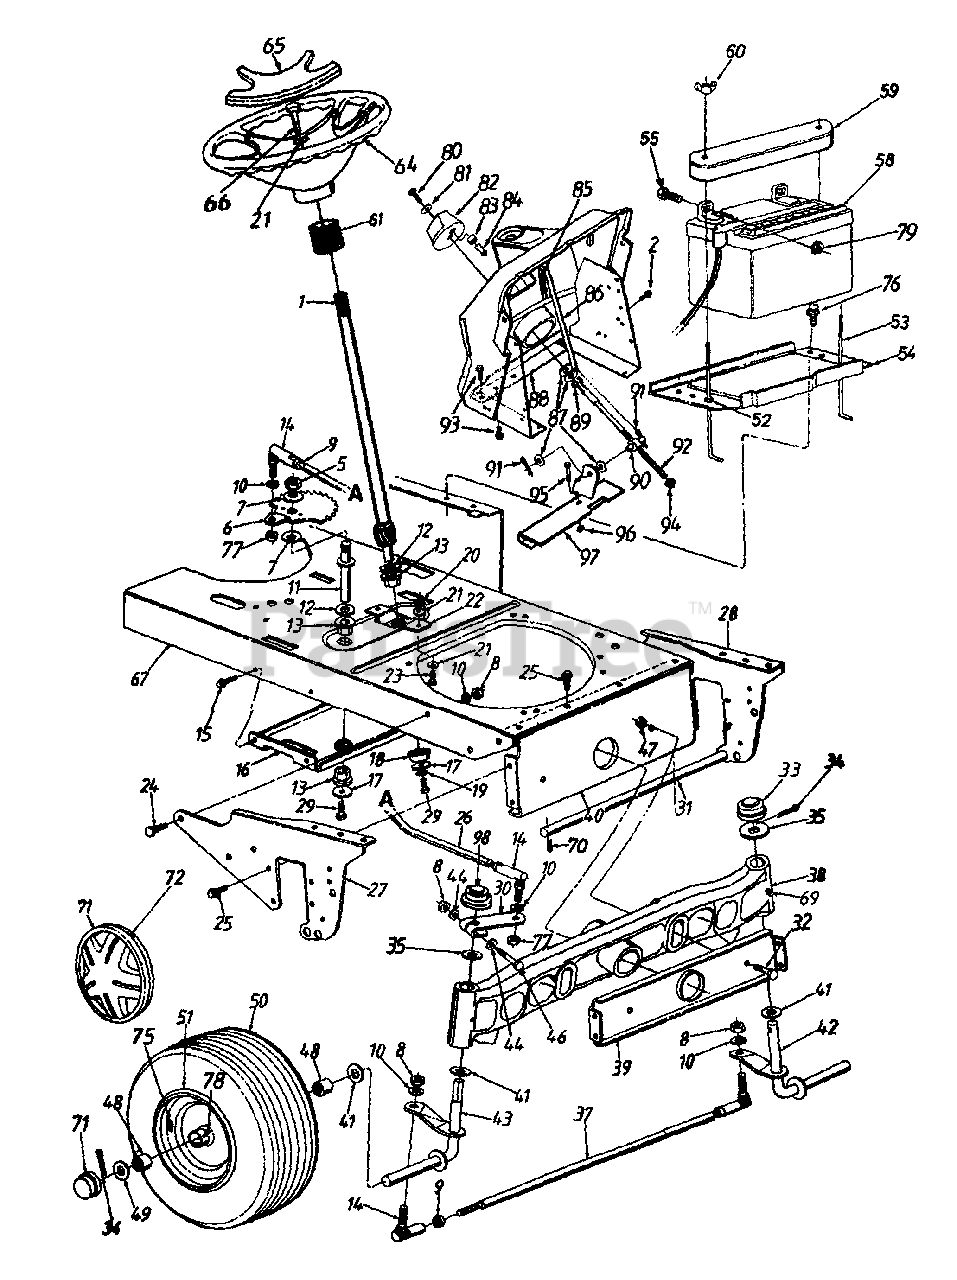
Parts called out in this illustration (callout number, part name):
1	Steering Shaft Ass'y.
5	Hex Nut 5/8-18 Thd.
6	Steering Gear Segment
7	Bell-Wash. 5/8" I.D. x 1.25" O.D.
8	Hex Nut 3/8-24 Thd.
9	Hex Jam Nut 3/8-24 Thd.
10	L-Wash. 3/8" I.D.
11	Steering Gear Segment Shaft
12	Fl-Wash. .64" I.D. x 1.24" O.D.
13	Hex Flange Brg. .63" I.D.
14	Ball Joint Ass'y.
15	Hex Wash. Hd. TT-Tap Scr. 1/4-20 x .5" Lg.
17	Fl-Wash. .33" I.D. x 1.25" O.D.
18	Spacer .985" I.D. x 1.25" O.D.
19	L-Wash. 5/16" I.D.
20	Hex Nut 5/16-24 Thd.
21	Bell-Wash. .345" I.D. x .88" O.D.
24	Ribbed Neck Bolt 3/8-24 x .8" Lg.
25	Hex Wash. TT-Tap Scr. 5/16-18 x .62" Lg.
26	Steering Drag Link
30	Steering Arm Ass'y.
31	Deck Connecting Rod
32	Shld. Bolt .498" Dia. x 2.45" Lg.
33	Cap
34	Cotter Pin 5/32" Dia.
37	Tie Rod 20.25" Lg.
38	Pivot Bar Ass'y.
41	Fl-Wash. .76" I.D. x 1.49" O.D.
42	Front Axle Ass'y. - L.H.
43	Front Axle Ass'y. - R.H.
44	Bowed Washer
46	Hex Bolt 3/8-24 x 2.25" Lg.
47	Hex L-Nut 3/8-16 Thd.
48	Ball Brg. .75" I.D.
49	Fl-Wash. .71" I.D. x 1.5" O.D.
53	Battery Hold Down Rod
58	Battery (275 Cold Crank Amps)
59	Battery Cover
60	Wing Nut Plastic 1/4-20 Thd.
61	Steering Bellow
64	Steering Wheel
65	Steering Wheel Insert
66	Hex L-Bolt 5/16-18 x 1" Lg.
70	Internal Cotter Pin
72	Spring Clip
75	Air Valve
76	Hex Wash. B-Tap Scr. 1/4" x .62" Lg.
77	Hex Jam L-Nut 3/8-24 Thd.
78	Grease Fitting
79	Hex Sems Nut 1/4-20 Thd.
80	Hex Cap Bolt 1/4-20 x .75" Lg.
81	Bell-Wash. .265" I.D. x .75" O.D.
82	Plastic Knob 3" Dia.
83	Spacer.38" I.D. x .5" O.D.
84	Ball Plunger
85	Ext. Spring 4.62" Lg.
86	Indicator Strip Ass'y.
87	Fl-Wash. 3/8" I.D. x .87" O.D.
90	Adjustment Ferrule
91	Hairpin Clip
92	Height Adjustment Rod
93	Hex Wash. TT-Tap Scr. 5/16-18 x .62" Lg.
94	Hex L-Nut 3/8-8 Twin Thd.
95	Hex Bolt 1/4-20 x 1.5" Lg.
96	Hex L-Nut 1/4-20 Thd.
